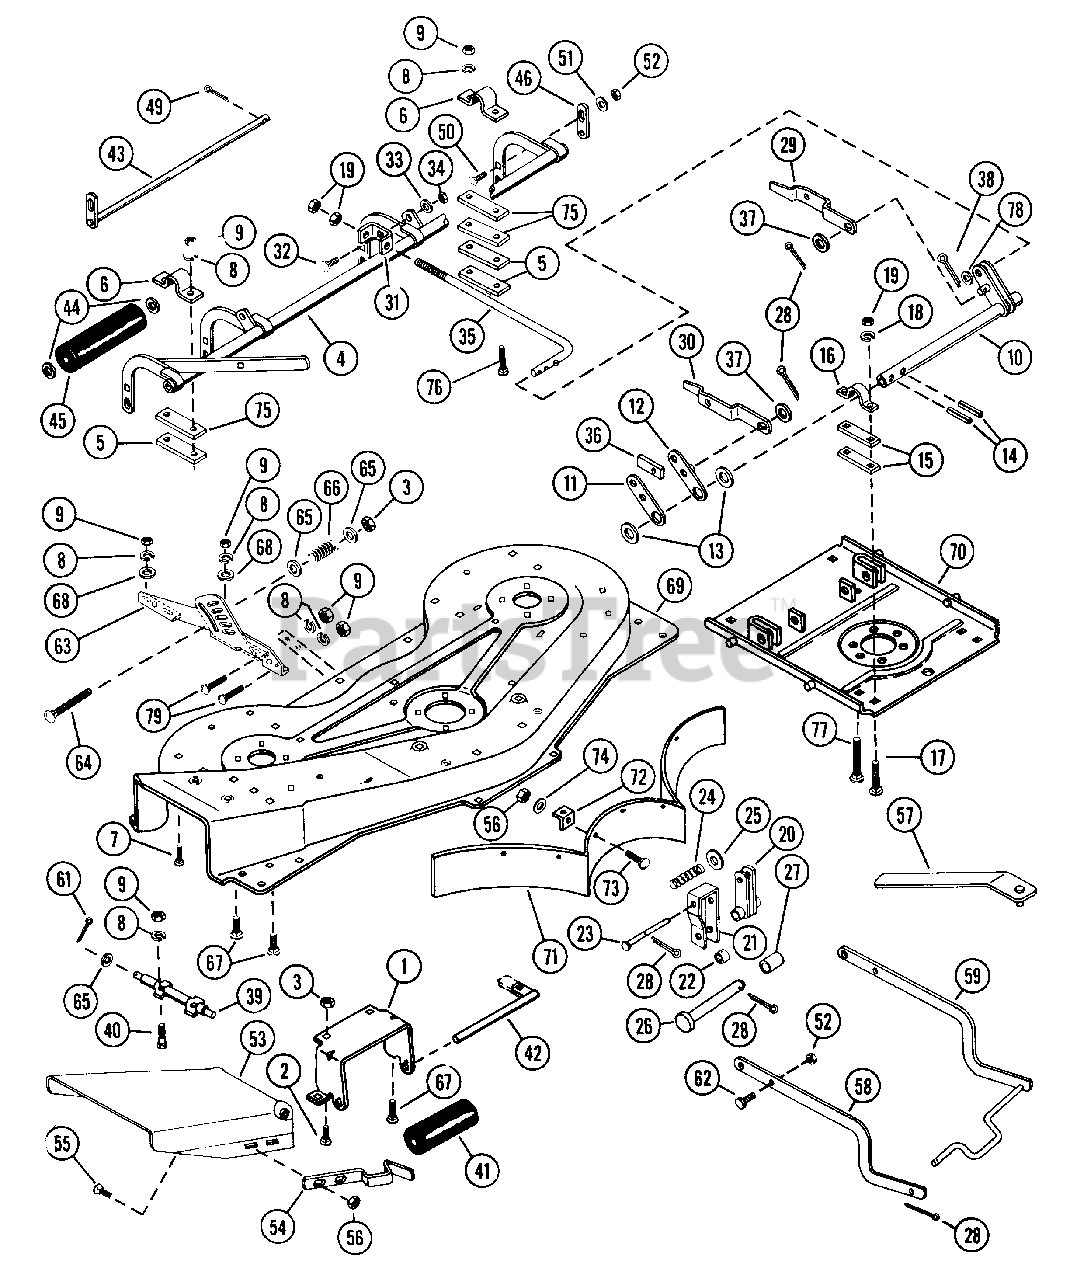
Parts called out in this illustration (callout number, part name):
1	BRACKET, ROLLER
2	BOLT, 5/16-18X.625 RD HD SQ NK
3	NUT, LOCK 5/16-18
4	ROLLER FRAME
5	SPACER
6	CLAMP
7	BOLT, CARRIAGE 5/16-18X2.75
8	WASHER, LOCK 3/8 SP HEAVY
9	NUT, HEX 5/16-18
10	FRONT HANGER
11	OUTSIDE LINK
12	INSIDE LINK
13	WASHER, FLAT .770X1.25X.06
14	PIN, SPRING .250X1.500
15	PLATE
16	CLAMP
17	BOLT, 1/2-13X1.50 RD HD SQ NK
18	WASHER, LOCK 1/2 SP HEAVY
19	NUT, HEX 1/2-13
21	CHANNEL
22	SPACER
23	PIN
24	SPRING
25	WASHER, FLAT .500X1.250X.083
26	PIN
27	SPACER
28	PIN, COTTER .125X1.00
29	LEVER, L.H.
30	LEVER, R.H.
32	BOLT, CARRIAGE 1/2-13X1.25
33	WASHER, FLAT .56X1.87X.109
34	NUT, LOCK 1/2-13
35	ROD, ADJUSTING
36	WEAR PLATE
37	WASHER, FLAT .506/.516X1.441X.125
38	PIN, COTTER .125X.75
39	PIN, HINGE
40	BOLT, HEX 5/16-18X.75
41	ROLLER
42	SHAFT, ROLLER
43	ROLLER SHAFT
44	WASHER, FLAT .656X1.312X.095
45	ROLLER
49	PIN, COTTER .187X1.25
50	BOLT, 3/8-16X1.00 RD HD SQ NK
51	WASHER, FLAT .438X1.000X.083
52	NUT, LOCK 3/8-16
53	CHUTE, EXTENSION
54	FLAT SPRING
55	BOLT, CARRIAGE 1/4-20X.5
56	NUT, LOCK 1/4-20
57	RAMP
58	ARM, HANGER
59	HANGER, MOWER
61	PIN, COTTER .09X.75
62	BOLT, HEX 3/8-16X1.00
63	HEIGHT QUADRANT
64	BOLT, CARRIAGE 5/16-18X1.75
65	WASHER, FLAT .406X.812X.065
66	SPRING
67	BOLT, CARRIAGE 5/16-18X.75
68	WASHER, FLAT .312X.734X.065
69	48-INCH DECK
70	MOUNTING PLATE
71	BAFFLE
72	BAFFLE TAB
73	BOLT, 1/4-20X.625 RD HD SQ NK
74	WASHER, FLAT .281X.625X.065
75	SPACER
76	BOLT, CARRIAGE 5/16-18X1.375
77	BOLT, CARRIAGE 1/2-13X1.75
78	WASHER, FLAT .219X.438X.049
79	BOLT, CARRIAGE 5/16-18X1.0
NS	WIDTH OF CUT DECAL
NS	DECAL, FLEX-N-FLOAT
NS	DECAL, WARNING
NS	DECAL, DANGER ROTATING BLADE
NS	DECAL, AMERICA
